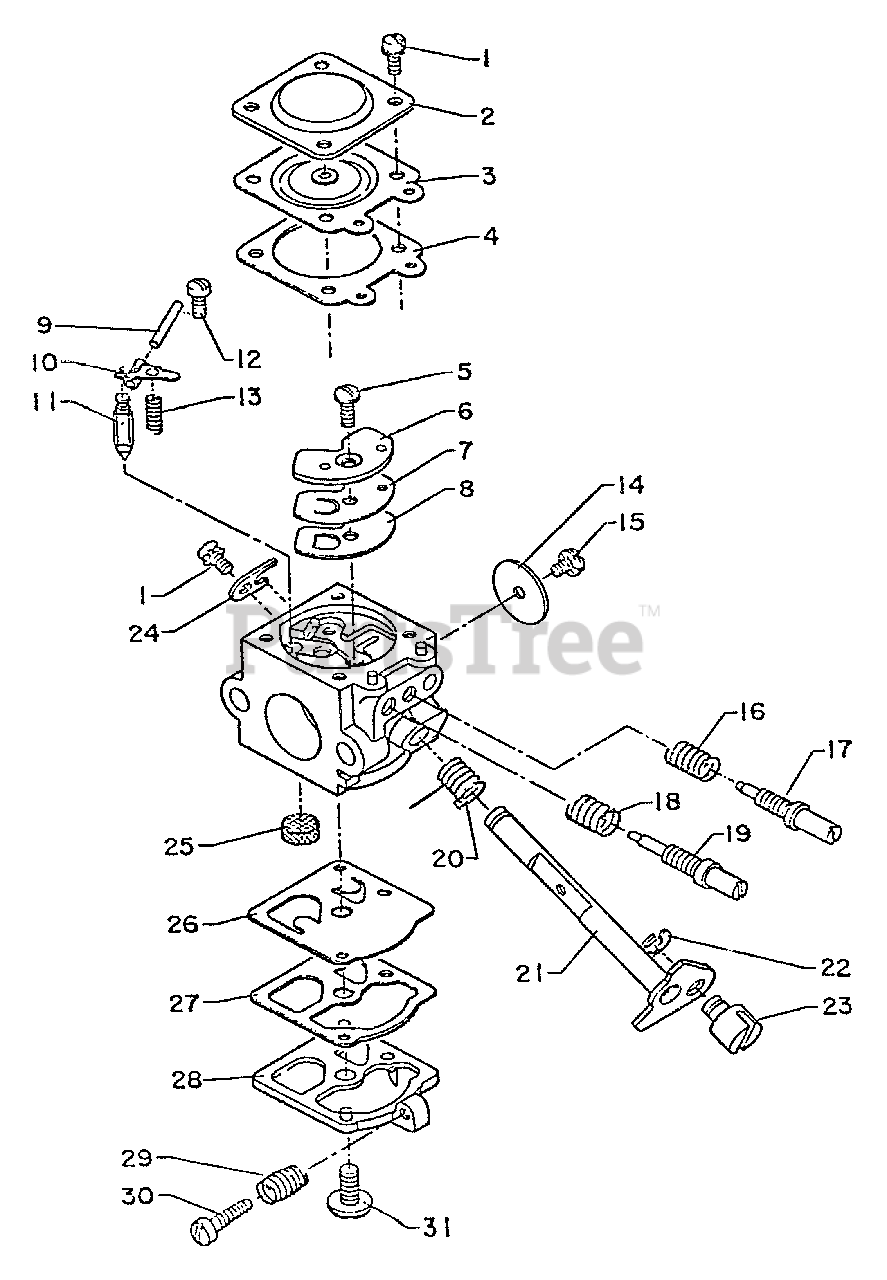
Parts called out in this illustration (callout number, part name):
2	COVER, METERING DIAPHRAGM
3	DIAPHRAGM, METERING
4	GASKET, METERING DIAPHRAGM
5	SCREW, CIRCUIT PLATE
6	PLATE, CIRCUIT
7	VALVE, CHECK
8	GASKET, CIRCUIT PLATE
9	PIN, METERING LEVER
10	LEVER, METERING
11	VALVE, INLET NEEDLE
12	SCREW, METERING LEVER PIN
14	VALVE, THROTTLE
16	SPRING, NEEDLE
17	NEEDLE, LOW SPEED
18	SPRING, NEEDLE
19	NEEDLE, HIGH SPEED
20	SPRING, THROTTLE RETURN
21	SHAFT, THROTTLE
22	RING, RETAINING
24	CLIP, THROTTLE SHAFT
25	STRAINER
26	DIAPHRAGM, FUEL PUMP
27	GASKET, FUEL PUMP
28	COVER, PUMP
29	SPRING, IDLE ADJUST
30	SCREW, IDLE ADJUST
